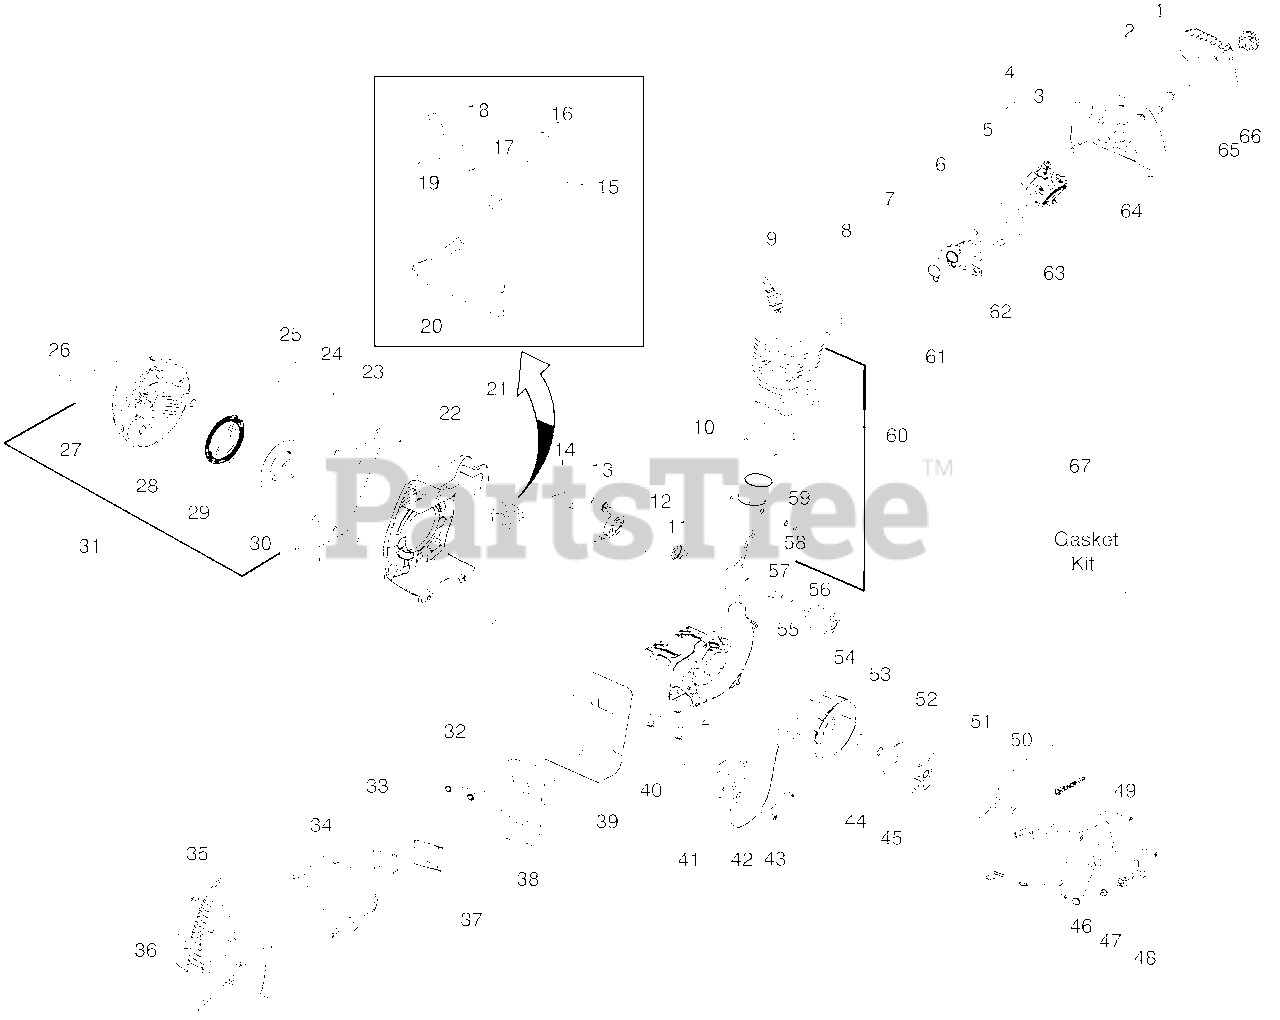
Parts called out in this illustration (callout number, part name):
2	Nut - Carb. Screw
3	Lever - Choke
4	Bulb - Purge
5	Kit-Carb. Gasket
6	Adaptor - Carb.
7	Foam - Gasket (kit)
9	Plug - Spark (RCJ-6Y)
10	Seal - Cylinder (kit)
11	Seal - Crankshaft (kit)
12	Washer
13	Assy - Starter Cup
14	Coupling - Starter
15	Assy - Fuel Filter
16	Kit - Fuel Line
17	Fitting - Fuel Line
18	Assy - Cap w/ret.
19	O-Ring - Fuel Cap (kit)
20	Isolator - Fuel Tank
21	Kit - Fuel Tank
22	Shroud - Rear
24	Kit - Rope
25	Handle - Starter
27	Starter Hsg. w/eyelet
28	Kit - Starter Spring
29	Kit - Starter Pulley
31	Assy-Starter Hsg.
32	Bolt - Muffler
33	Screw
34	Shield - Heat
36	Guard - Muffler
37	Kit – Spark
38	Kit - Muffler
39	Gasket-Paper Met.(kit)
41	Module
42	Assy - Leadwire
45	Washer - Clutch
50	Assy - Fan Housing
51	Assy - Clutch Drum
52	Kit - Clutch Assy.
55	Crankcase - cast
57	Crankshaft - Assy
58	Retainer - Piston Pin
59	Ring - Piston
60	Kit - Cyl./Piston
61	Seal - adaptor (kit)
62	Screw
63	Kit - Carb.
64	Airbox
65	Cover - Air Box
66	Assy - Knob
67	Kit - Gasket
